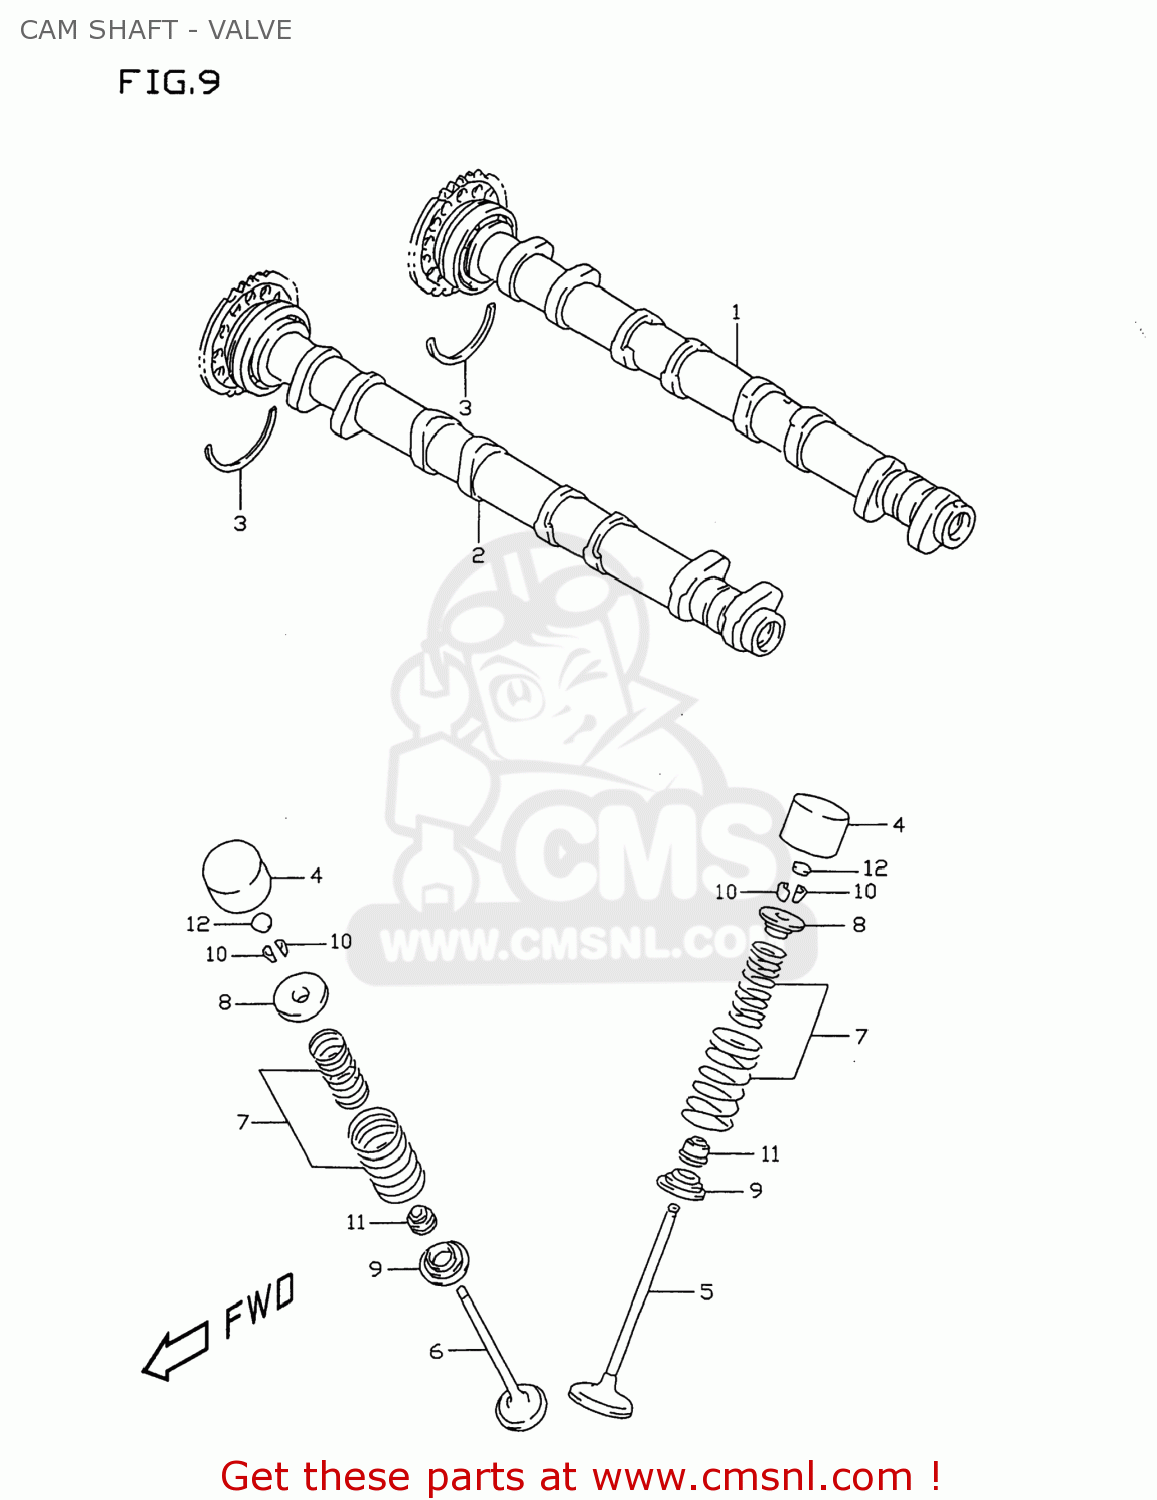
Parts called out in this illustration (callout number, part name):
1	CAMSHAFT,INTAKE
2	CAMSHAFT COMP,EXHAUST
3	C RING
4	TAPPET
5	VALVE,INTAKE
6	VALVE,EXHAUST
7	SPRING SET,VALVE
8	RETAINER,VALVE SPRING
9	SEAT,VALVE SPRING
10	COTTER VALVE
11	SEAL,OIL(4.5X10X8)
12	SHIM,TAPPET
13	SHIM SET,TAPPET
14	CASE,TAPPET SHIM
